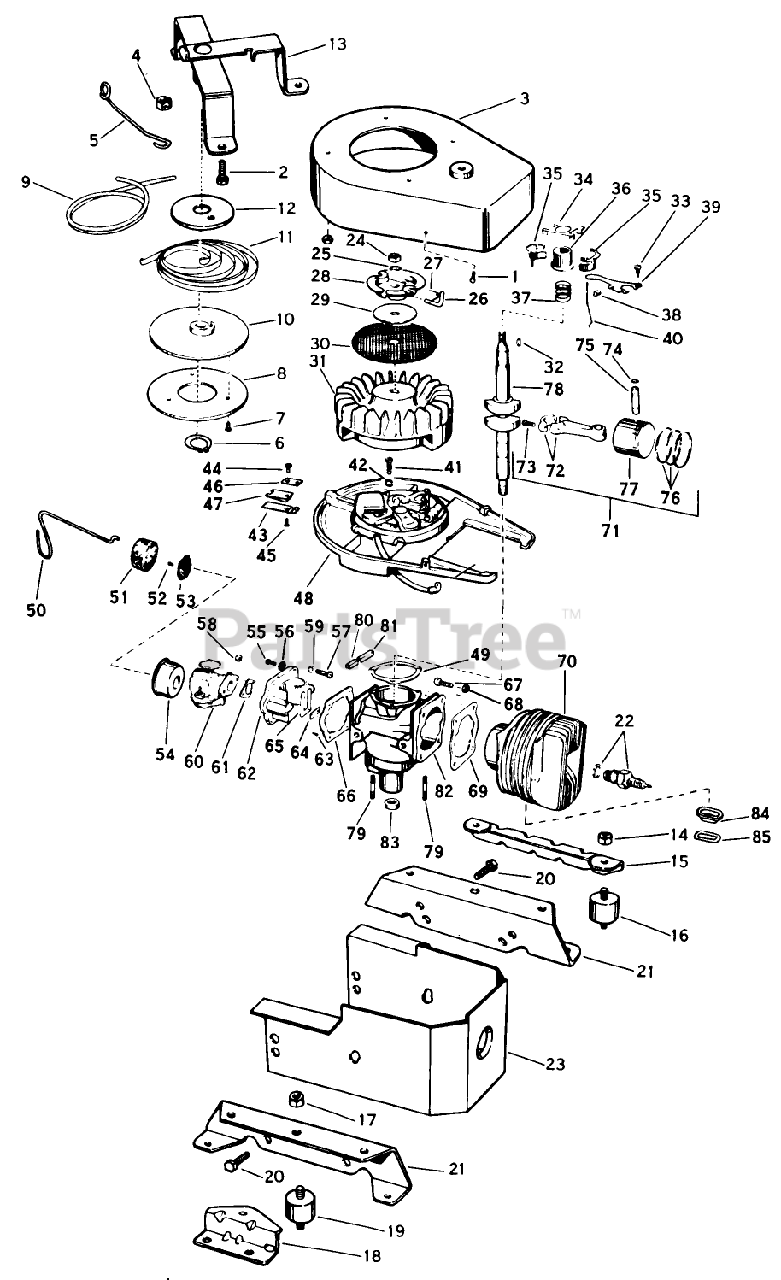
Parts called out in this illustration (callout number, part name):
1	SCREW S
6	Ring-Grip (Starter Brg. Pin)
8	Plate-Pulley
9	Rope-Starter
11	RECOIL SPRING
12	Washer-Starter Spring Ret.
15	Bracket-Shock Mounting, Housing, Left
16	Mount-Rubber, Left
18	Bracket-Shock Mounting, Housing, Right
19	Mount-Rubber, Right
20	Screw-Stabilizer Bracket
21	Bracket-Shock Mtg., Engine
22	Spark Plug
23	Shield-Cylinder and Crankcase
26	PIN - STARTER
36	COLLAR S
37	Spring-Governor
38	WEAR BLOCK S
39	GOVERNER LEVER AY
40	WEAR BLOCK S
45	Screw Shut-off Switch
47	Cover-Shut-off Switch Contact
49	GASKET S
50	Clip-Air Filter
51	ELEMENT
54	Cup-Air Filter
55	SCREW S
58	STOP NUT
61	GASKET S
64	PLATE-BACKUP, REED
66	GASKET
71	Piston and Con. Rod Assembly
73	Screw-Connecting Rod
78	Crankshaft
79	Stud-Crankcase to Muffler
80	Shield-Dust, Crankcase, Right
81	Shield-Dust, Crankcase, Left
